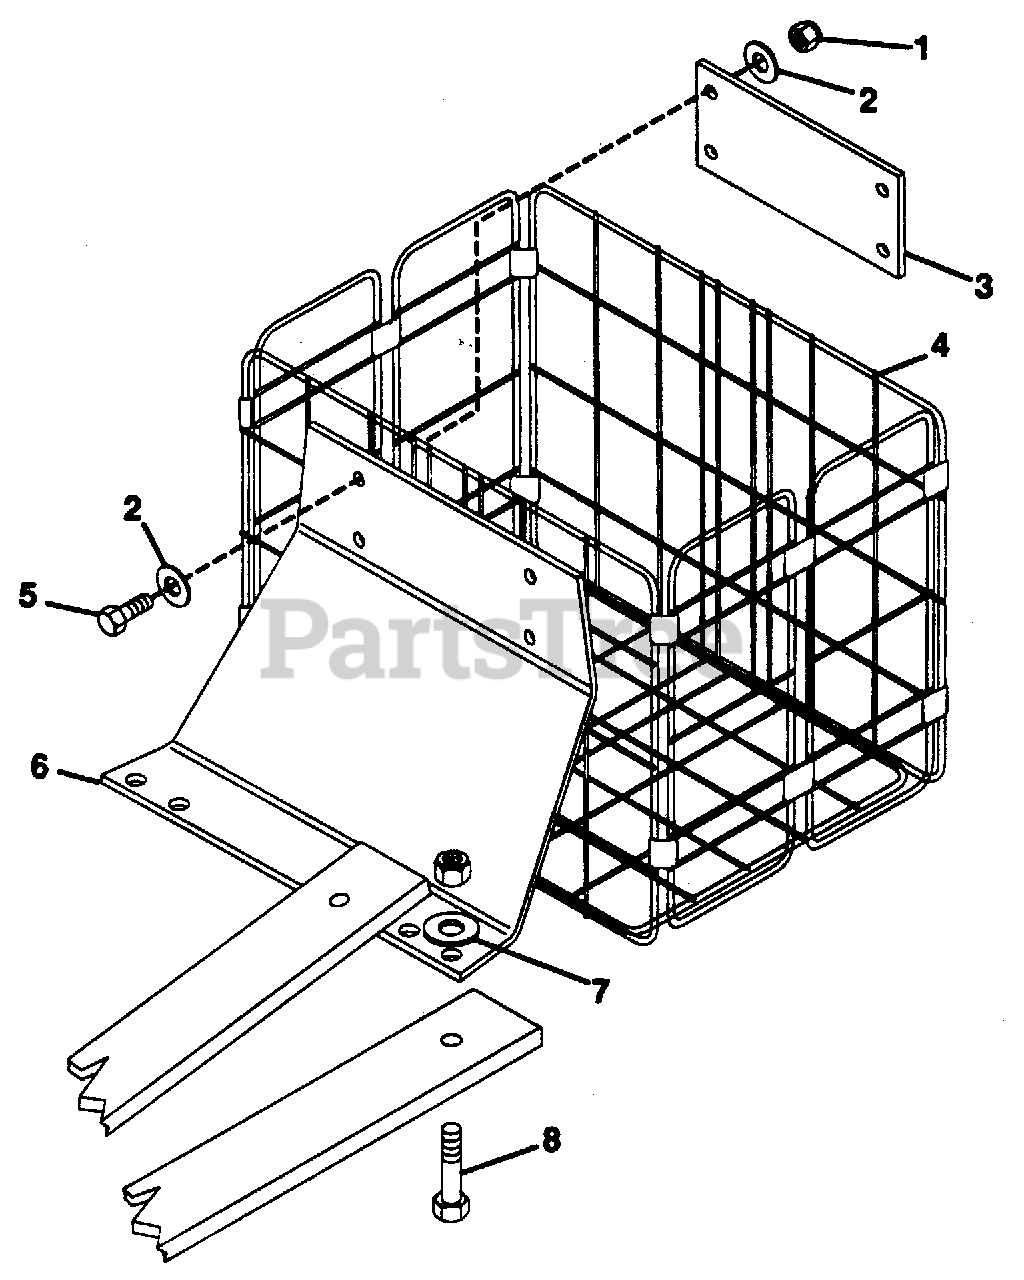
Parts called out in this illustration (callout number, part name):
1	Nut, Lock 1/4-20
2	Washer, Flat .281x.625x.065
3	Strap, Basket
4	Basket
5	Bolt, Hex 1/4-20x1.00
6	Bracket, Basket
7	Washer, Flat .344x.688x.065
8	Bolt, Hex 5/16-18x2.00
